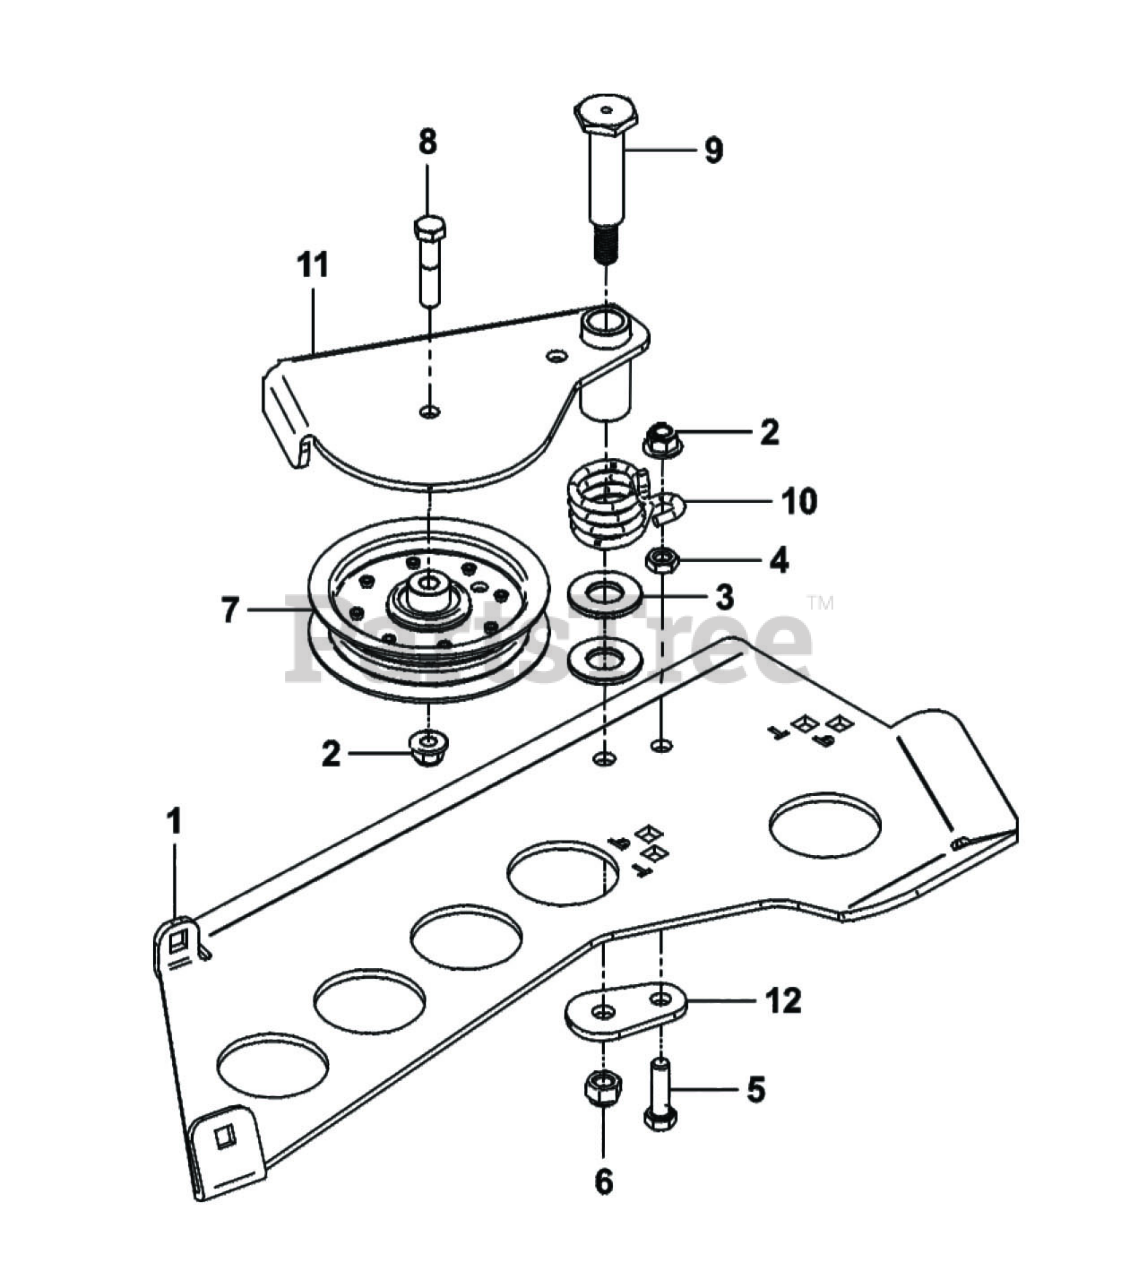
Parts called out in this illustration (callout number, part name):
1	IDLER MOUNT PLATE
2	LOCKNUT-NYLON FLAN
3	FLAT WASHER
4	JAM NUT 3/8"-16
5	BOLT-HEX 3/8-16 X
6	NYLOK NUT 7/16"-14 (GR8)
7	IDLER PULLEY
8	SCREW 3/8"-16 x 1.75" (GR8)
9	SHOULDER BOLT 7/16"-14
11	IDLER ARM ASSEMBLY
12	IDLER BASE PLATE
